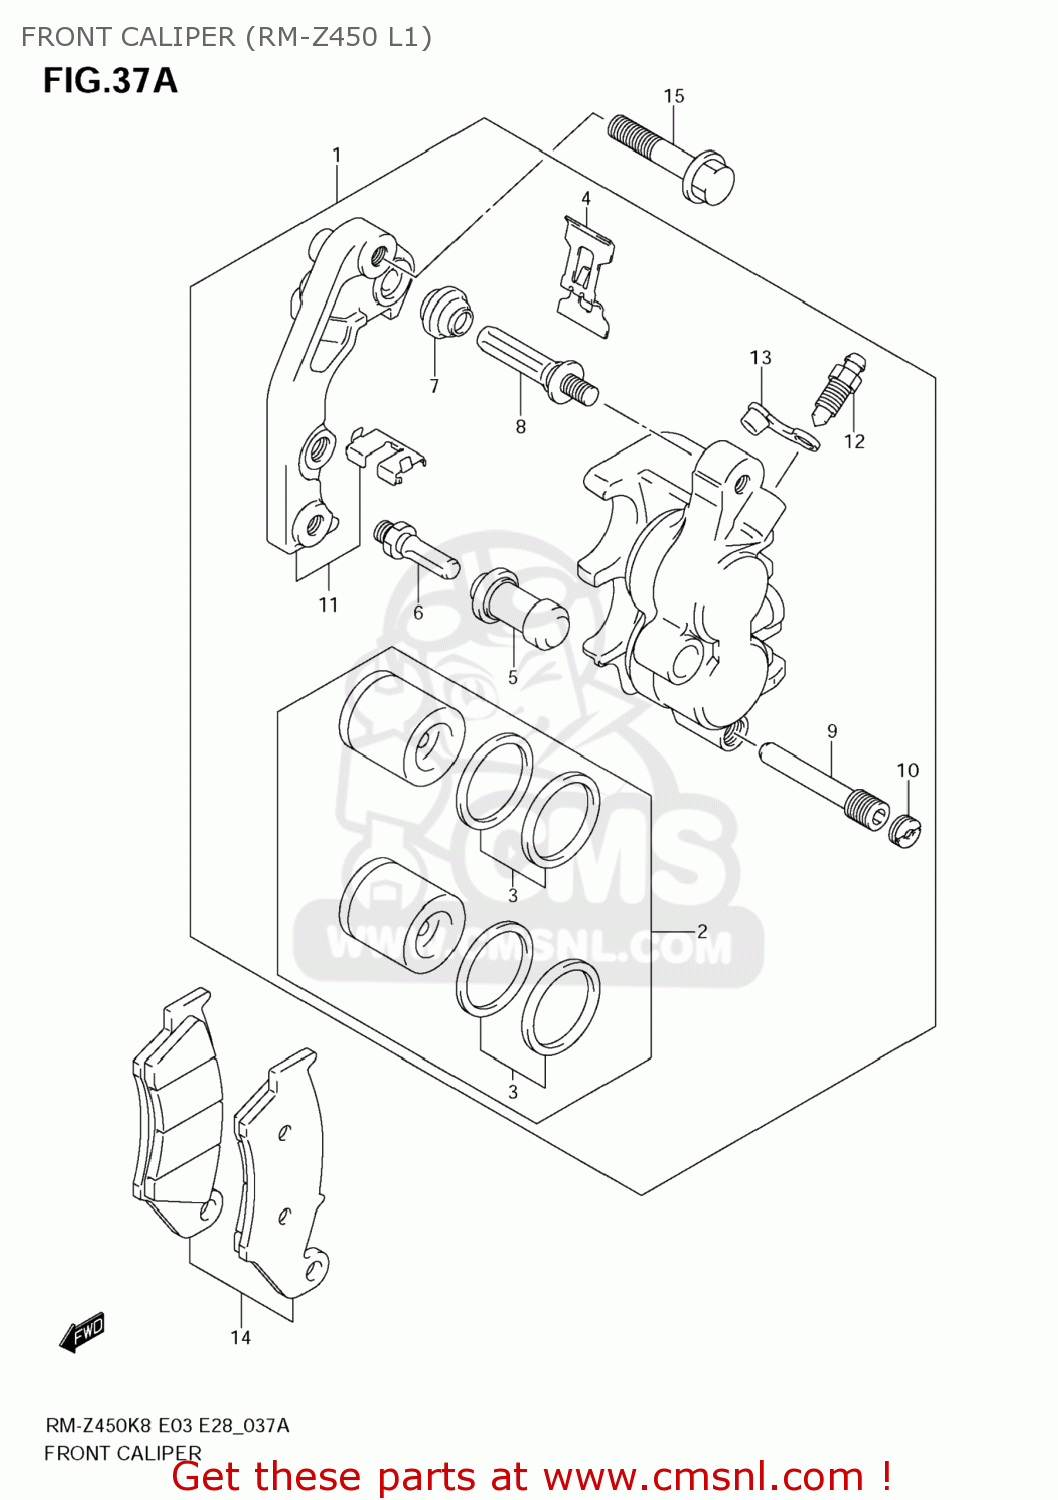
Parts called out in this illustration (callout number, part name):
1	CALIPER ASSY,FR
2	PISTON SET
3	SEAL SET,PISTON
4	SPRING,PAD
5	BOOT
6	BOLT
7	BOOT
8	PIN
9	PIN,HANGER
10	PLUG,PIN
11	BRACKET
12	BLEEDER
13	CAP,BLEEDER
14	PAD SET (NAS)
15	BOLT(8X41)
